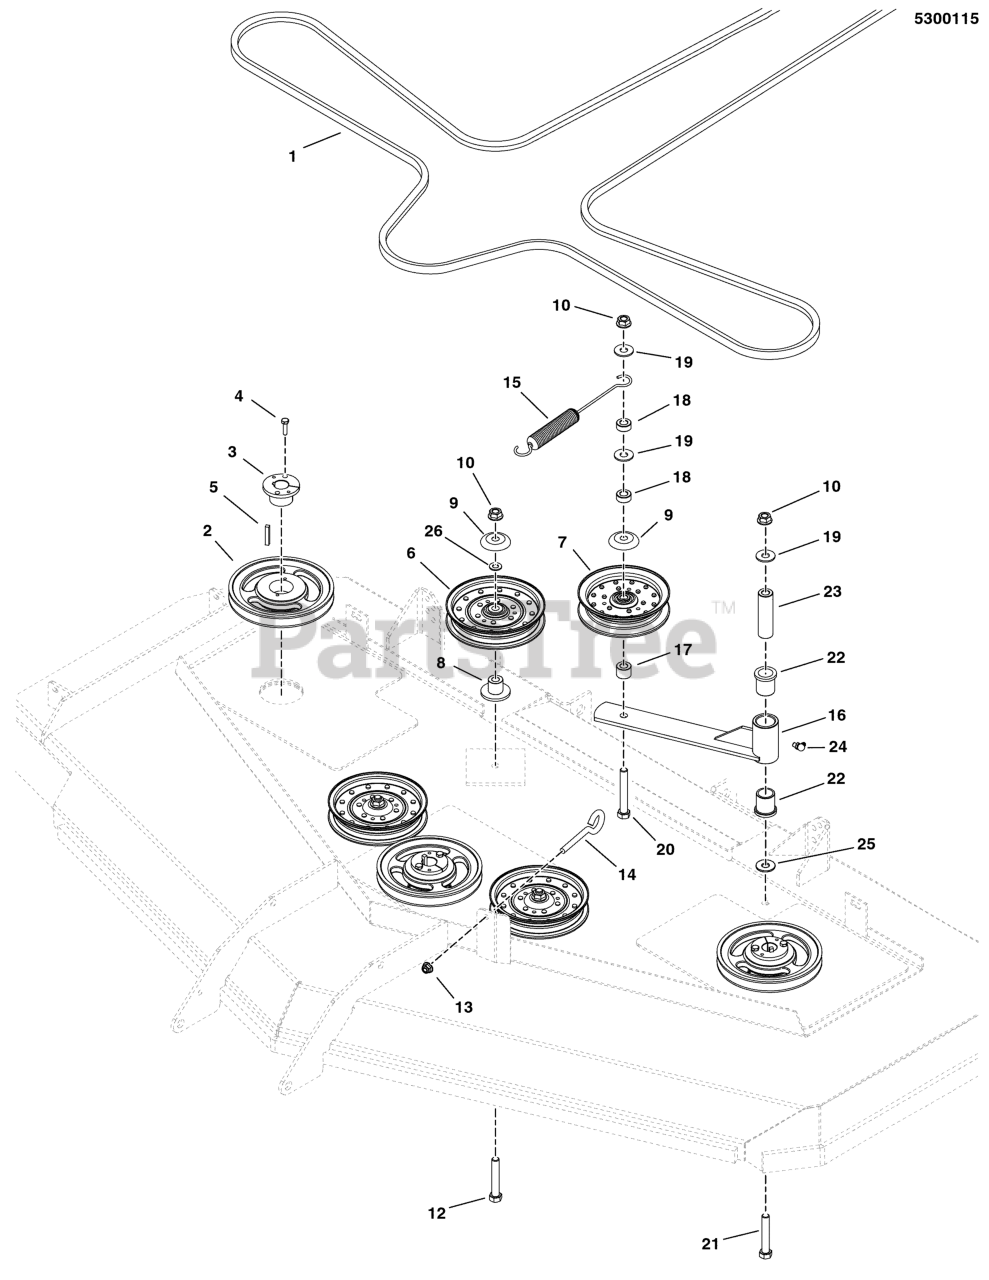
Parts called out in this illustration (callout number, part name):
1	BELT, SPB/XPB 193.9" EL, LRG ARAMID, 2T
2	PULLEY, SPINDLE, BH72
3	BUSHING, TAPERED HUB
4	BOLT, 1/4-20 X 1" GD5 CZ
5	KEY 1/4 SQ X 1 1/2 LONG
8	IDLER MOUNT
9	SHIELD, PULLEY BEARING
10	NUT, Hex Flange, Nylock, 1/2-13
11	BOLT, 1/2-13 X 2-3/4 GD5 CZ
12	BOLT, 1/2-13 X 3" GD5 CZ
13	NUT, 3/8-16 HEX NYLOCK FLANGE
14	EYE BOLT, 3/8-16 X 5, 2.88THRD, 1EYE, CZ
15	SPRING-EXT, 1.04 ODX10.535LGX.148WR, BLK
16	IDLER ARM ASSEMBLY
17	SPACER, .52 X 1.00 X .63, CZ
18	SPACER, .52 X 1.00 X .44, CZ
19	WASHER, 1/2 USS
20	BOLT, 1/2-13 X 3-1/2, HEX HD, GD5, CZ (SV)
21	BOLT-1/2-13 X 5 GD5
22	BUSHING, FLANGE
23	SPACER, .52 X 1.00 X 3.50
24	GREASE FITTING, 1/4-28, 90 DEGREE
25	WASHER, .52 X 1.75 X .14, CZ
26	WASHER, 1/2 SAE
